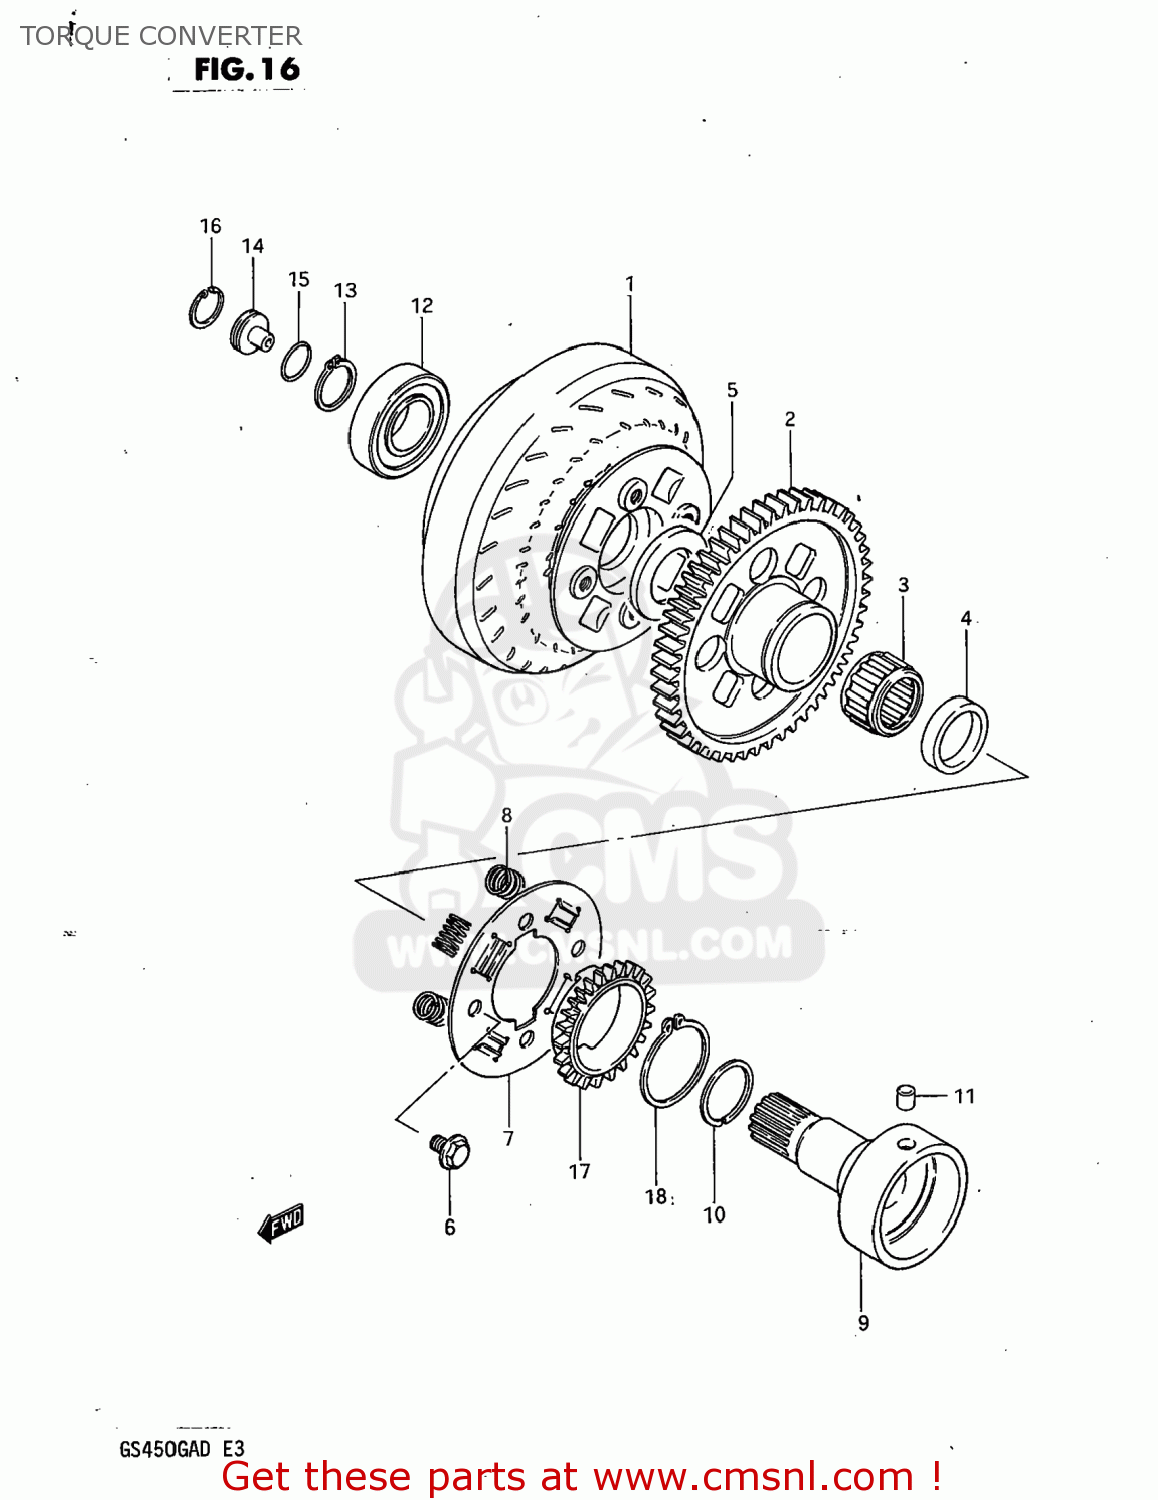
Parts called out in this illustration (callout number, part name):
1	GEAR ASSEMBLY,PRIMARY DRIVE
2	GEAR,PRIMARY DRIVEN
3	ROLLER BEARING (26X34X1
4	SPACER
5	SHIM
6	BOLT
8	SPRING
10	SPACER,PRIMARY DRIVEN
11	PIN
12	BEARING
13	CIRCLIP,25MM
15	O-RING (D:1.5 ID:15.2)
16	CIRCLIP
17	GEAR,OIL PUMP DRIVE
18	CIRCLIP
